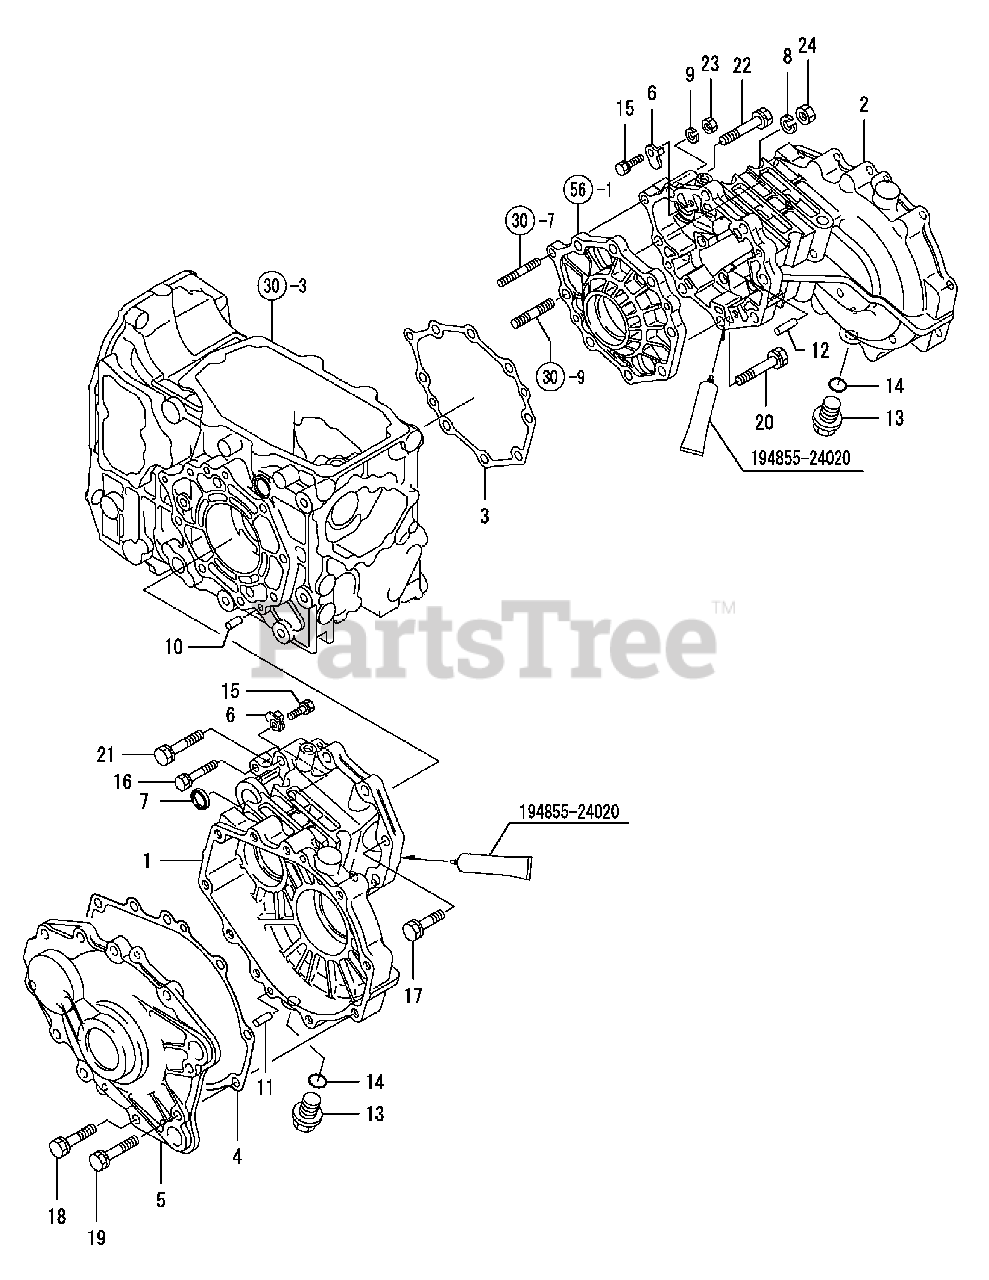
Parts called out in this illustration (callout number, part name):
1	Housing, Rear Axle L
2	Housing, Rear Axle R
3	Packing, Housing
5	Cover, Rear Axle
6	Stopper,Steel Plate
7	Seal Tc253506,Oil
8	Spring Washer 10
9	Locking Washer
10	Parallel Pin, M8X16
11	Parallel Pin, M8X20
12	Parallel Pin, M8X32
14	O-Ring 1A P-16.0
15	Bolt W/Washer M8X20
22	Bolt 10X65 W/Sp.Wshr
